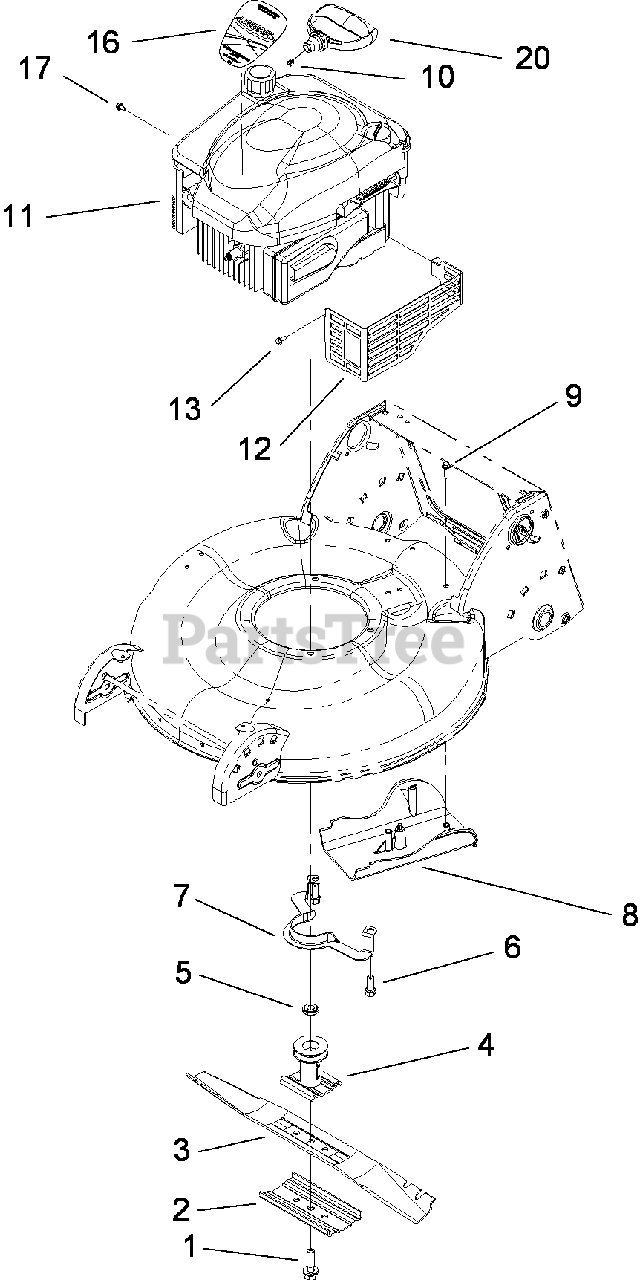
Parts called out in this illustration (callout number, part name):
1	BOLT-BLADE
2	SUPPORT-BLADE
3	BLADE-21 INCH
4	BLADE DRIVER ASM
5	Spacer-Driver
6	SCREW-HWH
8	COVER-BELT
9	SCREW-HWH
10	STOP-ROPE
12	SHIELD-MUFFLER
13	SCREW-TAPTITE
16	DECAL-ENGINE
17	SCREW-HWH
20	HANDLE-RECOIL
